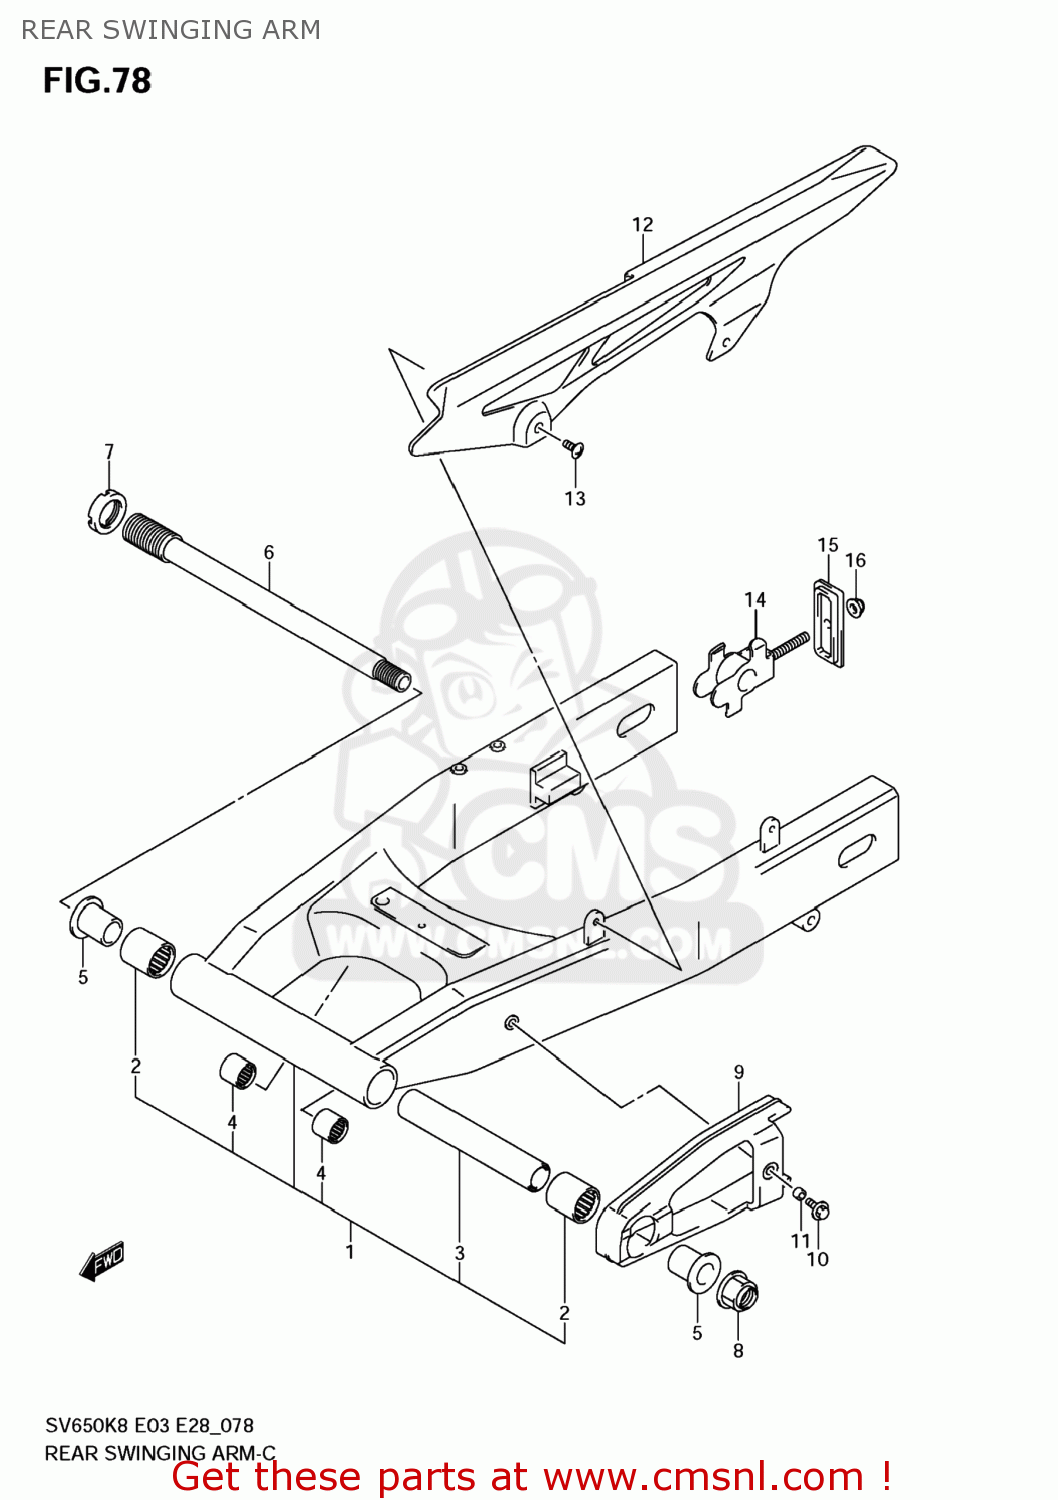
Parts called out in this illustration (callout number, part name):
1	SWINGINGARM ASSY,RR
2	BEARING(25X33X35)
3	SPACER(20.8X27.2X161)
4	BEARING(17X24X20)
5	SPACER,RR SWGARM PIVOT BERRING
6	SHAFT,RR SWINGINGARM PIVOT
7	NUT,REAR SWING ARM PIVOT BOLT
8	NUT
9	BUFFER,CHAIN TOUCH DEFENSE
10	BOLT(6X20)
11	SPACER(6.5X9X5)
12	CASE,CHAIN
13	SCREW(6X16)
14	ADJUSTER,CHAIN
15	GUIDE,CHAIN ADJUSTER
16	NUT
